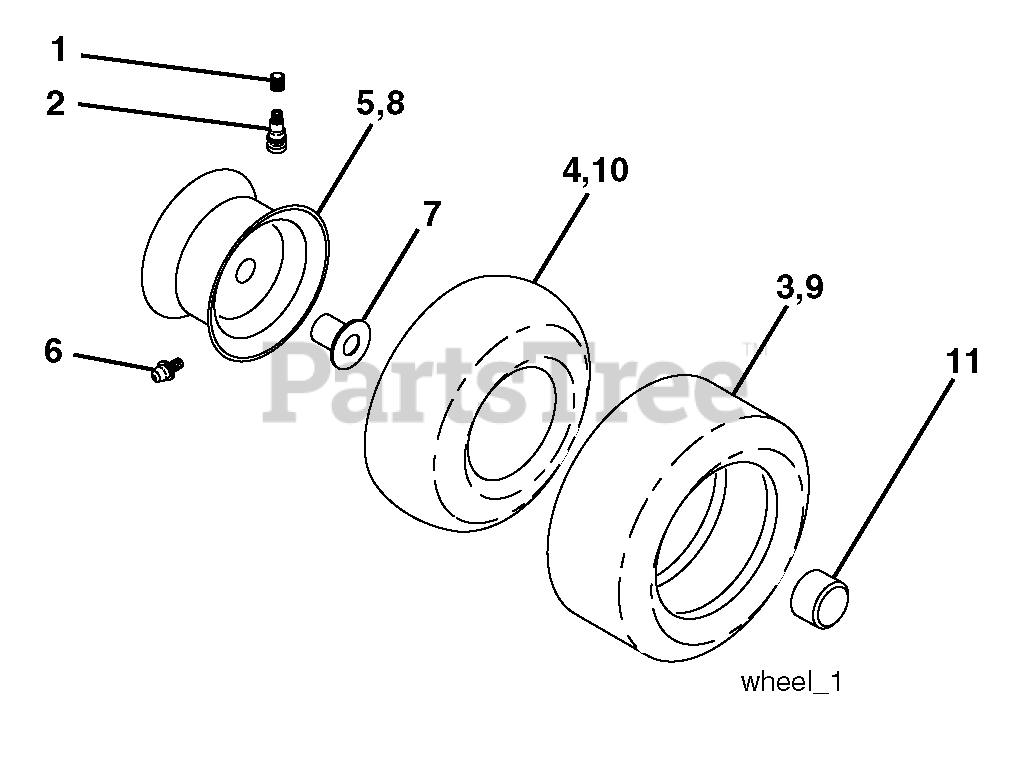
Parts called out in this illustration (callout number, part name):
1	Cap Valve Tire
2	Stem Valve
3	Tire F T 15 x 6 0 - 6
4	Tube Front
5	Rim Asm 6" Front
6	Fitting Grease
7	Bearing Flange
8	Rim Asm 8" Rear
9	Tire R T 18 x 9.5-8 Turf Saver
9	Tire R T 18 x 9.5-8 Turf Saver LT
10	Tube Rear
11	Cap Axle Blk 1 50 x 1 00
11	Sealant, Tire (10 oz. Tube)
